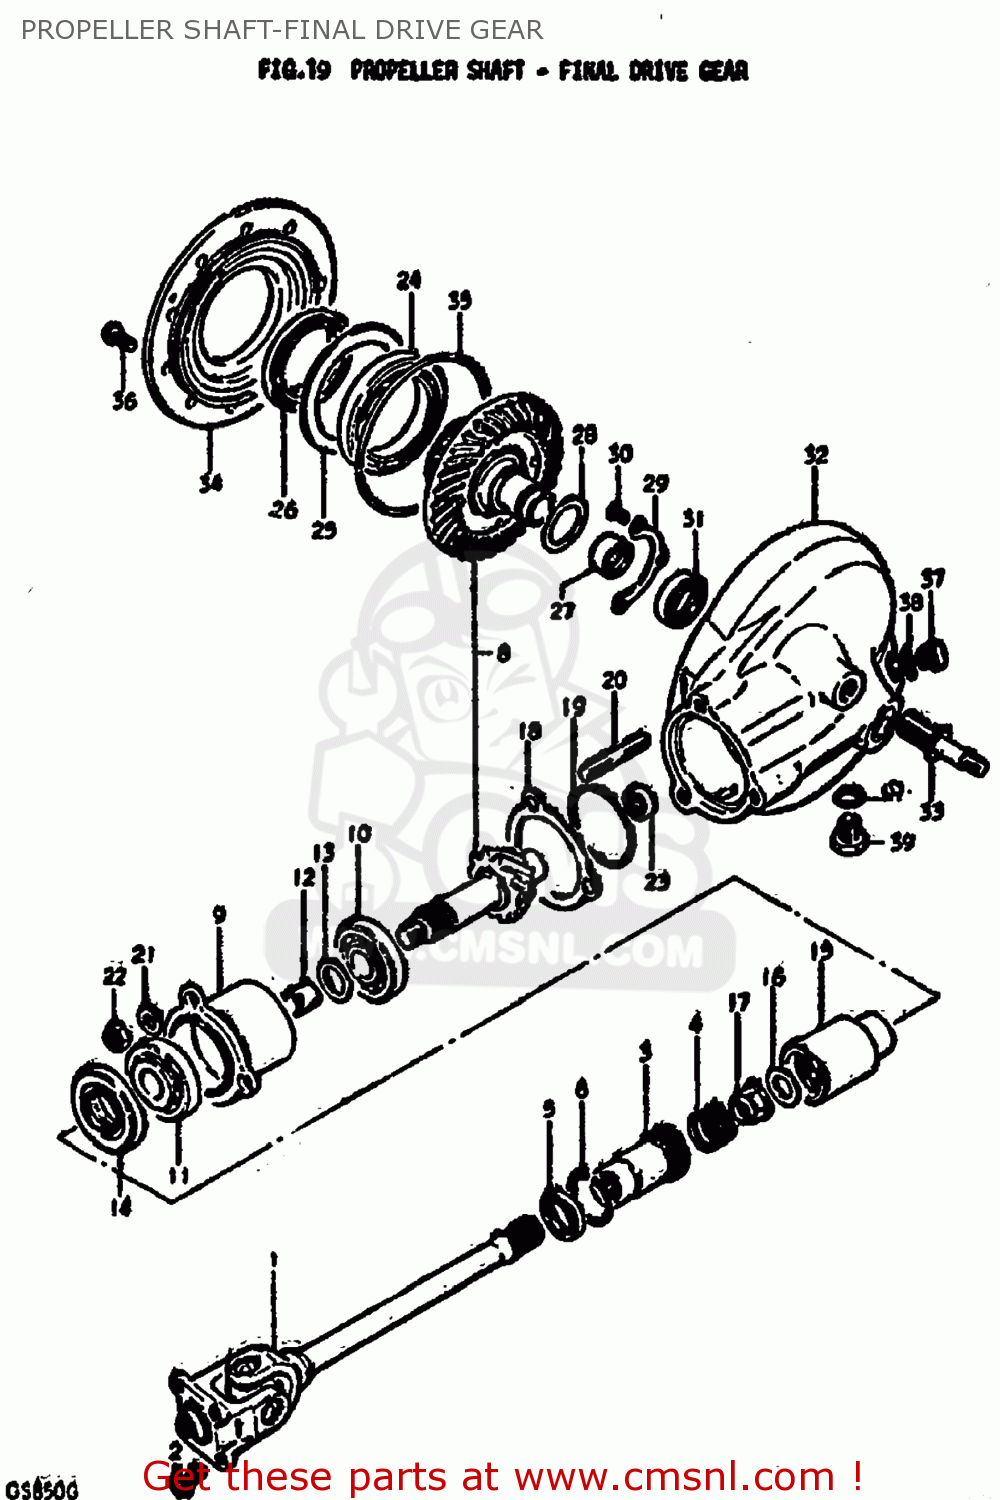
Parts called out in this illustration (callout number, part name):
1	SHAFT ASSEMBLY,PROPELLER
2	BOLT 8X16
3	COUPLING,PROPELLER SHAFT
4	SPRING
5	SEAL,OIL(30X40.5X5.5)
6	CIRCLIP
7	FINAL BEVEL GEAR & CASE
8	GEAR SET,FINAL BEVEL
9	HOUSING,DRIVE GEAR
10	BEARING(25X52X19.25)
11	BEARING
12	SPACER (25.2X30X3.5)
13	SHIM (25X30X2
14	SEAL,OIL(32X54X7)
15	GEAR,FINAL DRIVE
16	WASHER(14X29X4)
17	NUT
18	SHIM,DRIVE GEAR HOUSING
19	O RING(D:2.4,ID:62.6)
20	STUD 10X30
21	LOCK WASHER
22	NUT
23	BEARING(24X33X17)
24	BEARING(70X110X13)
25	SHIM,DRIVEN GEAR BEARING
26	SEAL,OIL(70X96X16)
27	BEARING(35X48X23.7)
28	SHIM,FINAL DRIVEN GEAR
29	RETAINER,FINAL DRIVEN GEAR BRG
30	SCREW 6X12
31	SEAL,OIL(30X42X7)
32	CASE ASSEMBLY,FINAL GEAR
33	STUD
34	CASE,FINAL GEAR BEARING
35	O-RING (D:3.1 ID:144.4)
36	BOLT
37	PLUG (14X12)
38	GASKET(14X19.2X2) (NAS)
39	PLUG
40	GASKET(14X19.2X2) (NAS)
